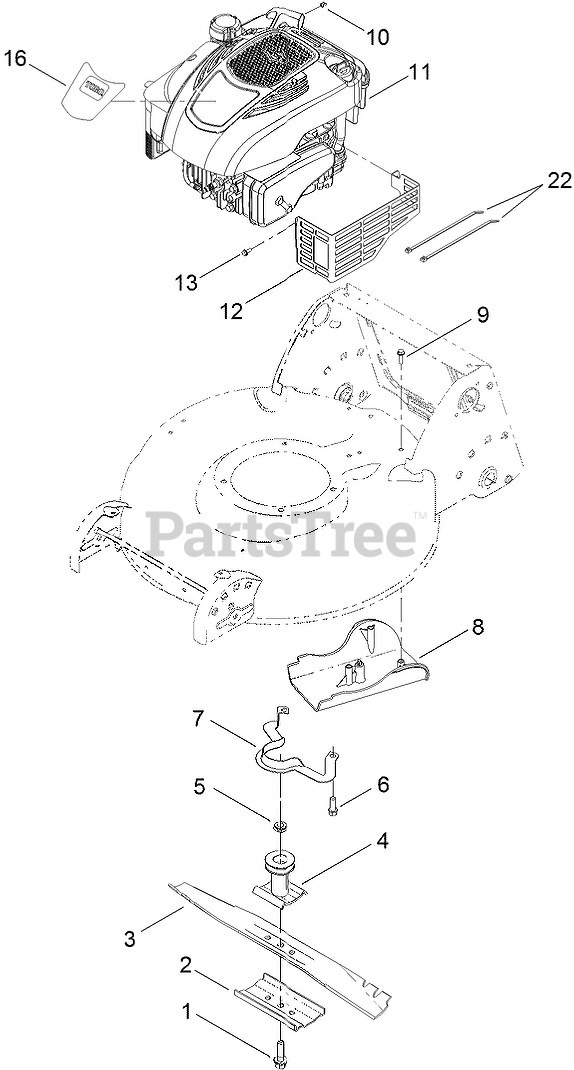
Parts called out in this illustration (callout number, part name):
1	BOLT-BLADE
2	SUPPORT-BLADE
3	BLADE-21 INCH
4	DRIVER-BLADE
5	Spacer-Driver
6	SCREW-TAPTITE
7	Guide-Belt
8	COVER-BELT
9	SCREW-HWH
10	STOP-ROPE
12	SHIELD-MUFFLER
13	SCREW-TAPTITE
16	DECAL-SHROUD
22	TIE-CABLE
